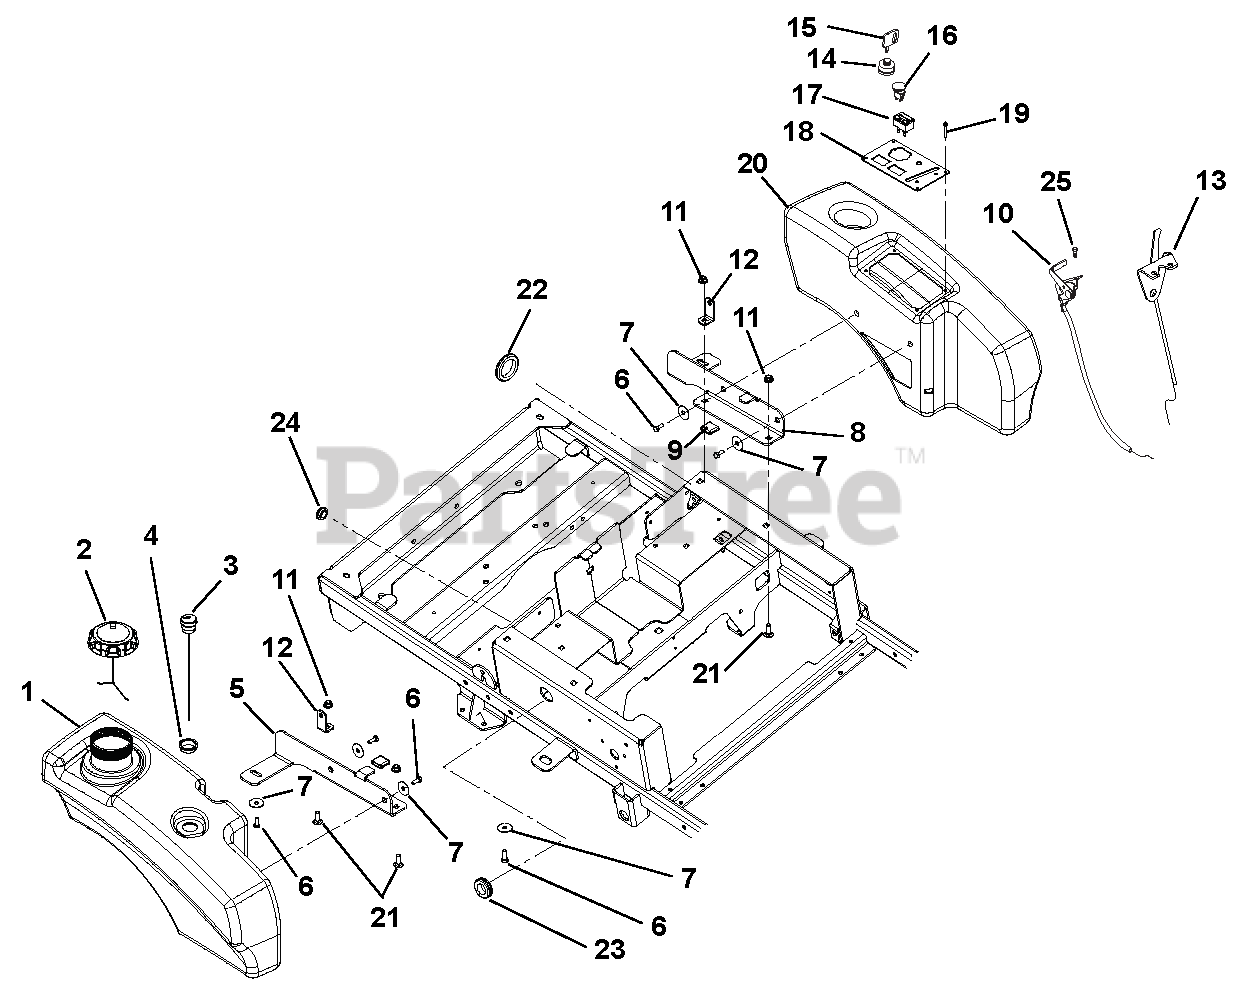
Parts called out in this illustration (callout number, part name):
1	TANK,ASSEMBLY XL CE
2	CAP, FUEL
3	GAUGE, REMOTE FUEL 10.0"
4	GROMMET, FUEL GAGE
5	BRKT, RH REAR TANK MOUNT
6	BLT-SERHFWH .312-18X.50 YWZC
7	WSHR-FL-STL .347X1.254X.048YWZ
8	BRKT, LH REAR TANK MOUNT
9	GRIP, RUBBER (1.0X1.0X.187)BLK
10	CABLE-THROTTLE
11	@NUT-LK-NYL-FLG .38-16 YWZC
12	BRKT, HOOD PIVOT
13	CABLE, CHOKE
14	KEY SWITCH
15	KEY -W/CAP
16	SWITCH, CLUTCH
17	METER, HOUR W/MAINTENANCE
18	CONTROL PANEL
19	RIVET, PLASTIC .195 DIA.
20	FENDER, XL
21	@BLT-RDHDSQNK .38-16X1.00 G5YZ
22	GROMMET 1.70ID X 2.0OD
23	GROMMET 1.0ID X 1.38 OD
24	GROMMET,RUBBER 5/8 ID/1.13 OD
25	@SCR-TAP 10-24X.50 HWH TR YWZC
